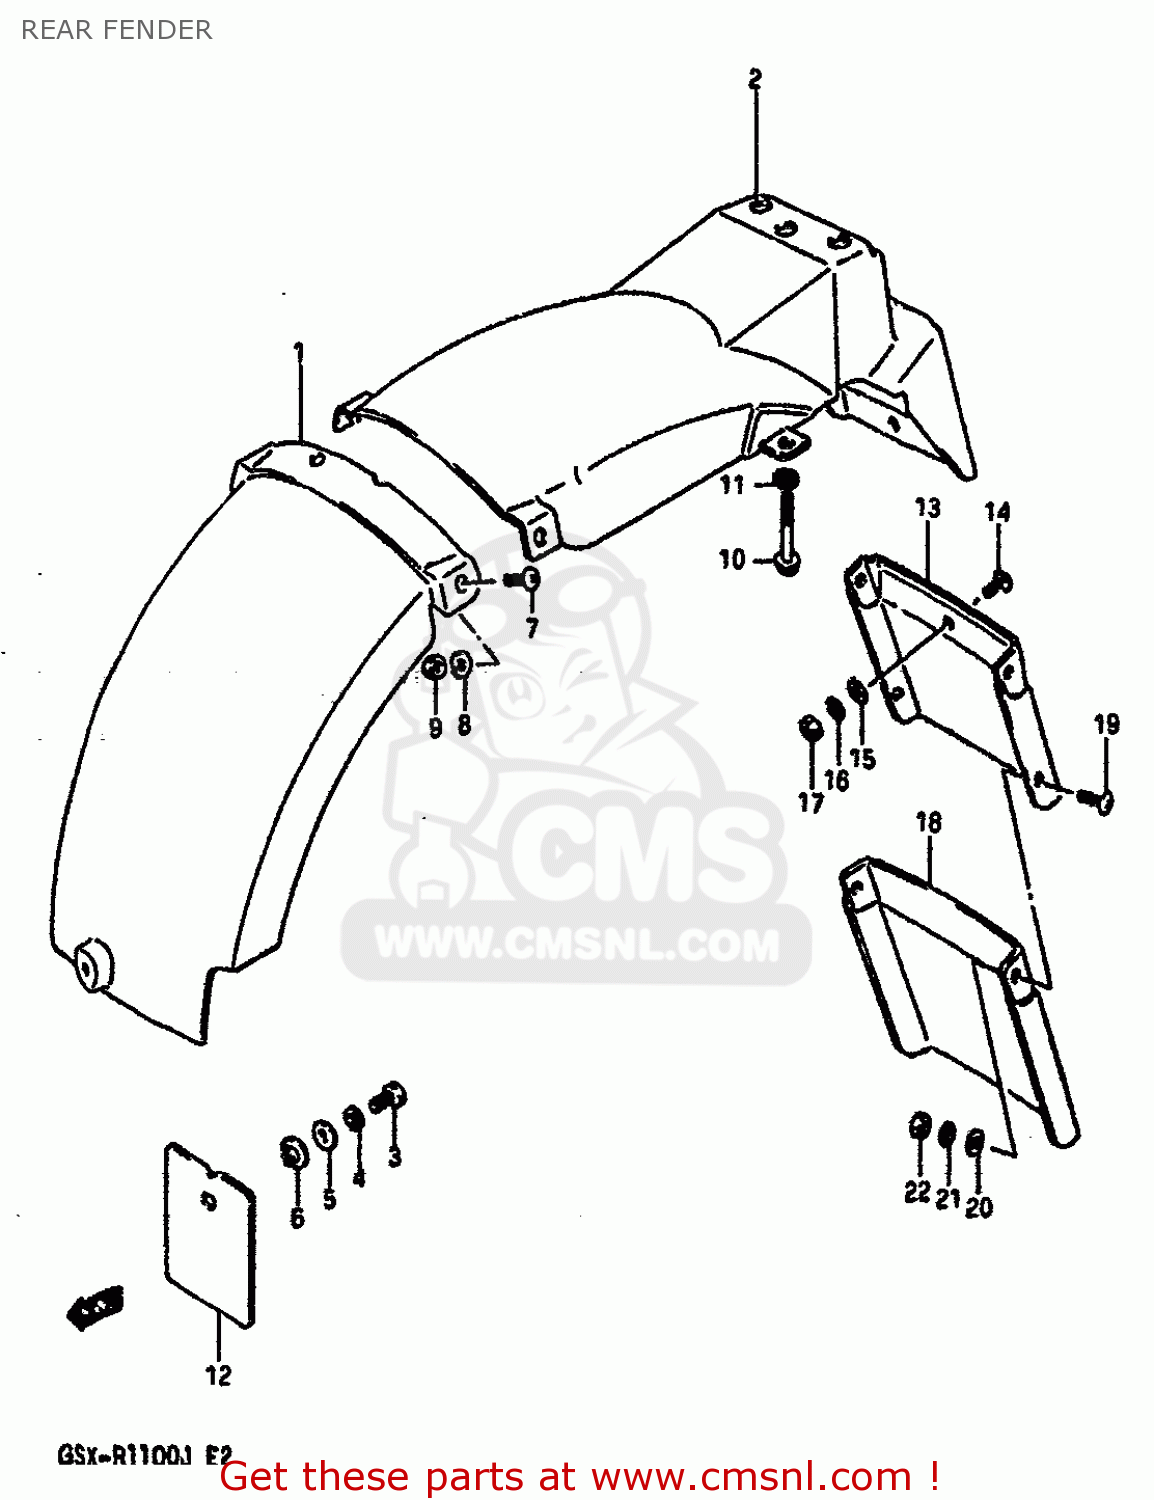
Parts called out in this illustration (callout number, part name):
1	BODY,REAR FENDER,FRONT
2	FENDER,REAR
3	BOLT
4	WASHER,LOCK
5	WASHER
6	WASHER
7	SCREW
8	WASHER
9	NUT 6MM
10	BOLT
11	WASHER
12	MUD GUARD,REAR FENDER,FRONT
13	EXTENSION
14	SCREW 6X12
15	WASHER
16	WASHER,LOCK
17	NUT
18	MUD GUARD
19	SCREW
20	WASHER(6.5X16X1.2)
21	WASHER,LOCK
22	NUT
